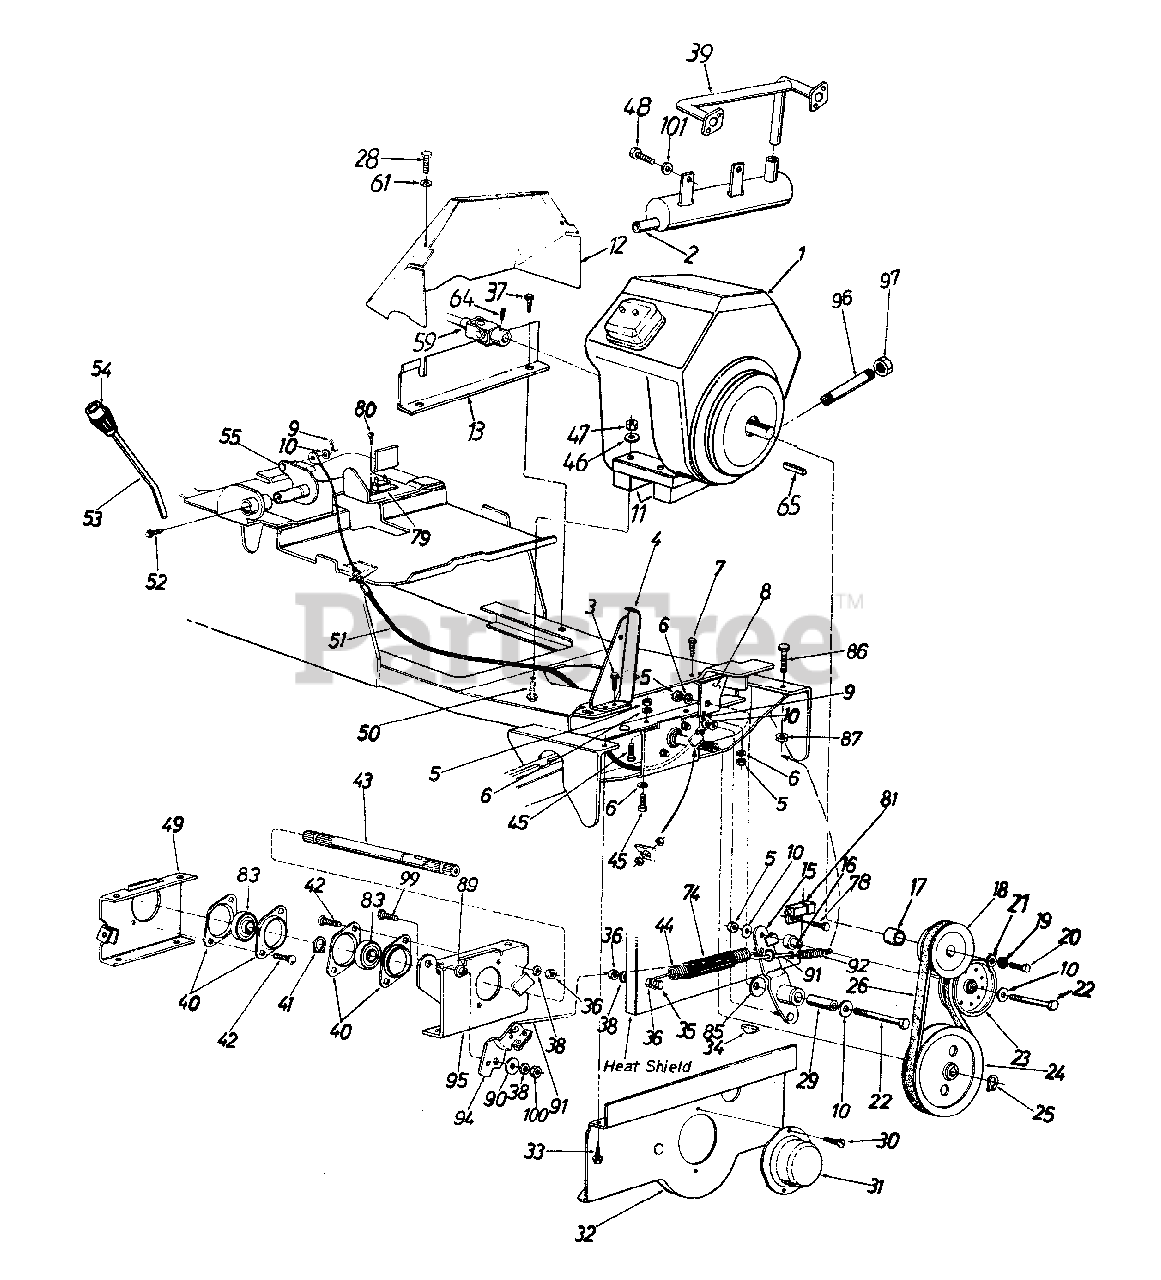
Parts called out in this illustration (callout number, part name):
1	Engine (Kohler)
2	Muffler
3	Hex Wash. Hd. Self-Tap Scr. 1/4-20 x .75"
6	L-Wash. 3/8" I.D.
7	Hex Wash. Hd. Self-Tap Scr. 5/16-18 x .75" Lg.
10	Fl-Wash. .38" I.D. x 1.25" O.D. x .100" Thk.
11	Engine Mounting Spacer
12	Heat Shield
13	Heat Baffle-Lower
17	Pulley Spacer
18	Engine PTO-Pulley
19	L-Wash. 3/8" I.D.
20	Hex Bolt 3/8-16 x 1" Lg.
21	Fl-Wash. 3/8" I.D. x 1.37" O.D.
22	Hex Bolt 3/8-16 x 2.50" Lg.
23	Flat Idler Pulley
24	1/2" V-Pulley 7.00" O.D. (PTO)
25	Snap Ring
26	V-Belt (PTO)
28	Hex Bolt M6-1.0 x 10mm Lg.
29	Spacer .375" I.D. x .62" O.D. x 1.830" Lg.
30	Hex B Tap Scr. #10 x .50" Lg.
34	#91 Hi-Pro Key
35	Hex Bolt 5/16-18 x 1.25" Lg.
36	Hex Nut 5/16-18 Thd.
37	Hex Wash. Hd. Tap Scr. 5/16-18 x .5" Lg.
38	L-Wash. 5/16" I.D.
39	Exhaust Pipe
40	1.00" Dia. Brg. w/Flangette
41	Snap Ring
42	Carr. Bolt 5/16-18 x .75" Lg.
43	Spline Shaft
44	Extension Spring (PTO Clutch)
45	Hex Bolt 3/8-16 x 1" Lg.
46	L-Wash. 3/8" I.D.
47	Hex Nut 3/8-16 Thd.
48	Hex Bolt 7/16-14 x 1" Lg.
49	PTO Bearing Retainer Brkt.
50	Hex Bolt 3/8-16 x 2.25" Lg.
51	PTO Control Cable
52	Hex TT-Tap Scr. 1/4-20 x .5" Lg.
53	PTO Handle
54	Shift Knob
55	PTO Actuator Lever Assembly
59	Universal Drive Shaft Comp.
61	Fl-Wash. .281" I.D. x .5" O.D.
64	Set Scr. 5/16-18 x .38" Lg.
65	Sq. Key 1/4" x 2" Lg.
74	Spring Cover Tubing (PTO Clutch)
78	Hex Bolt 1/4-20 x 1/2" Lg.
79	Circuit Breaker
80	Truss Mach. Scr. #10 x .50" Lg.
81	Safety Switch (PTO)
83	Ball Bearing
85	Bell-Wash. .39" I.D. x 1.13"
86	Hex Bolt 3/8-16 x 1.5" Lg.
87	Hex L-Nut 3/8-16 Thd.
89	Shoulder Spacer
90	Fl-Wash. .33" I.D. x 1.25" O.D.
91	PTO Brake Rod
92	Extension Spring 2.15" Lg.
94	Brake Assembly
95	PTO Brg. Retainer Brkt. Assembly
96	Pipe Nipple 3/8" x 5" Lg.
97	Oil Drain Cap
99	Hex Bolt 5/16-24 x .75" Lg.
100	Hex Nut 5/16-24 Thd.
101	L-Wash. 7/16" I.D.
